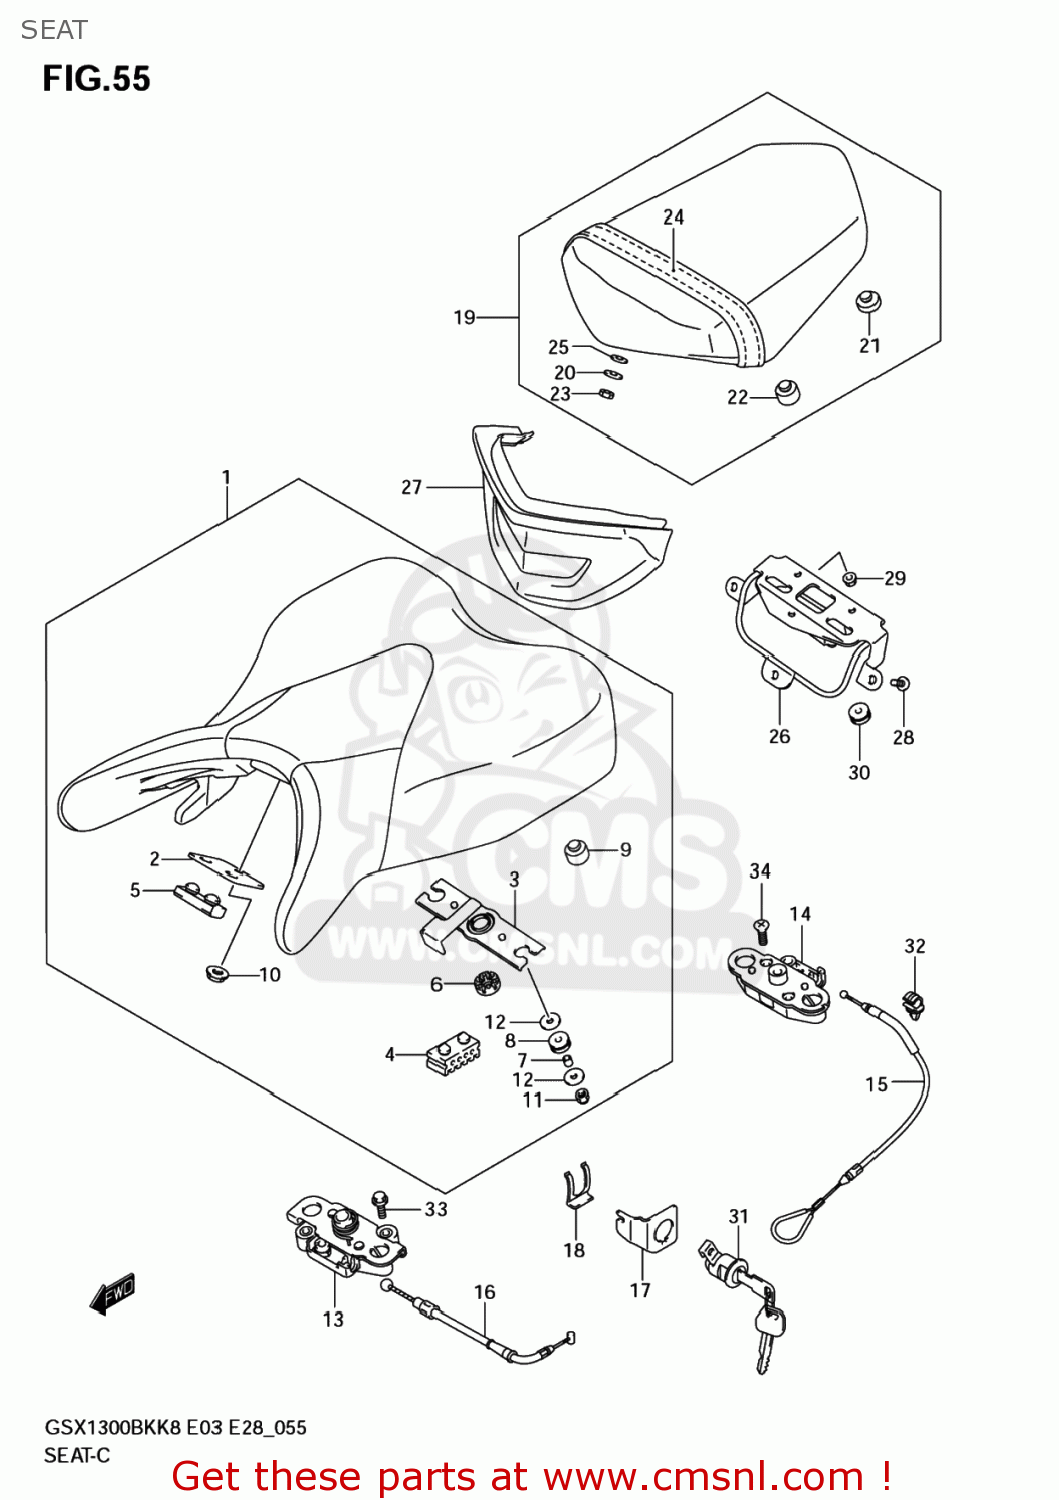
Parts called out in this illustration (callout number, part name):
1	SEAT ASSY
2	PLATE,SEAT FR
3	STRIKER,SEAT LOCK
4	CUSHION,RR
5	CUSHION,SEAT FR
6	CUSHION,SEAT LOCK(10X22X6)
7	SPACER(6X9.8X6)
8	CUSHION
9	CUSHION
10	NUT
11	NUT
12	WASHER(6.5X20X2)
13	BRACKET,STRIKER SUPPORT
14	BRACKET,SEAT SUPPORT,RIGHT
15	CABLE,SEAT LOCK RR
16	CABLE,SEAT LOCK
17	GUIDE,SEAT LOCK CABLE
18	PLATE,SEAT LOCK ASSY
19	SEAT ASSY,PILLION
20	WASHER(6.5X18X1.6)
21	CUSHION,FR
22	CUSHION
23	NUT
24	BAND,PILLION SEAT GRIP
25	WASHER
26	BRACKET,PILLION SEAT
27	COVER,PILLION SEAT FR(BLACK)
28	SCREW
29	NUT
30	CUSHION,SEAT LOCK(10X22X6)
31	LOCK SET,SEAT
32	CLAMP
33	BOLT
34	SCREW
